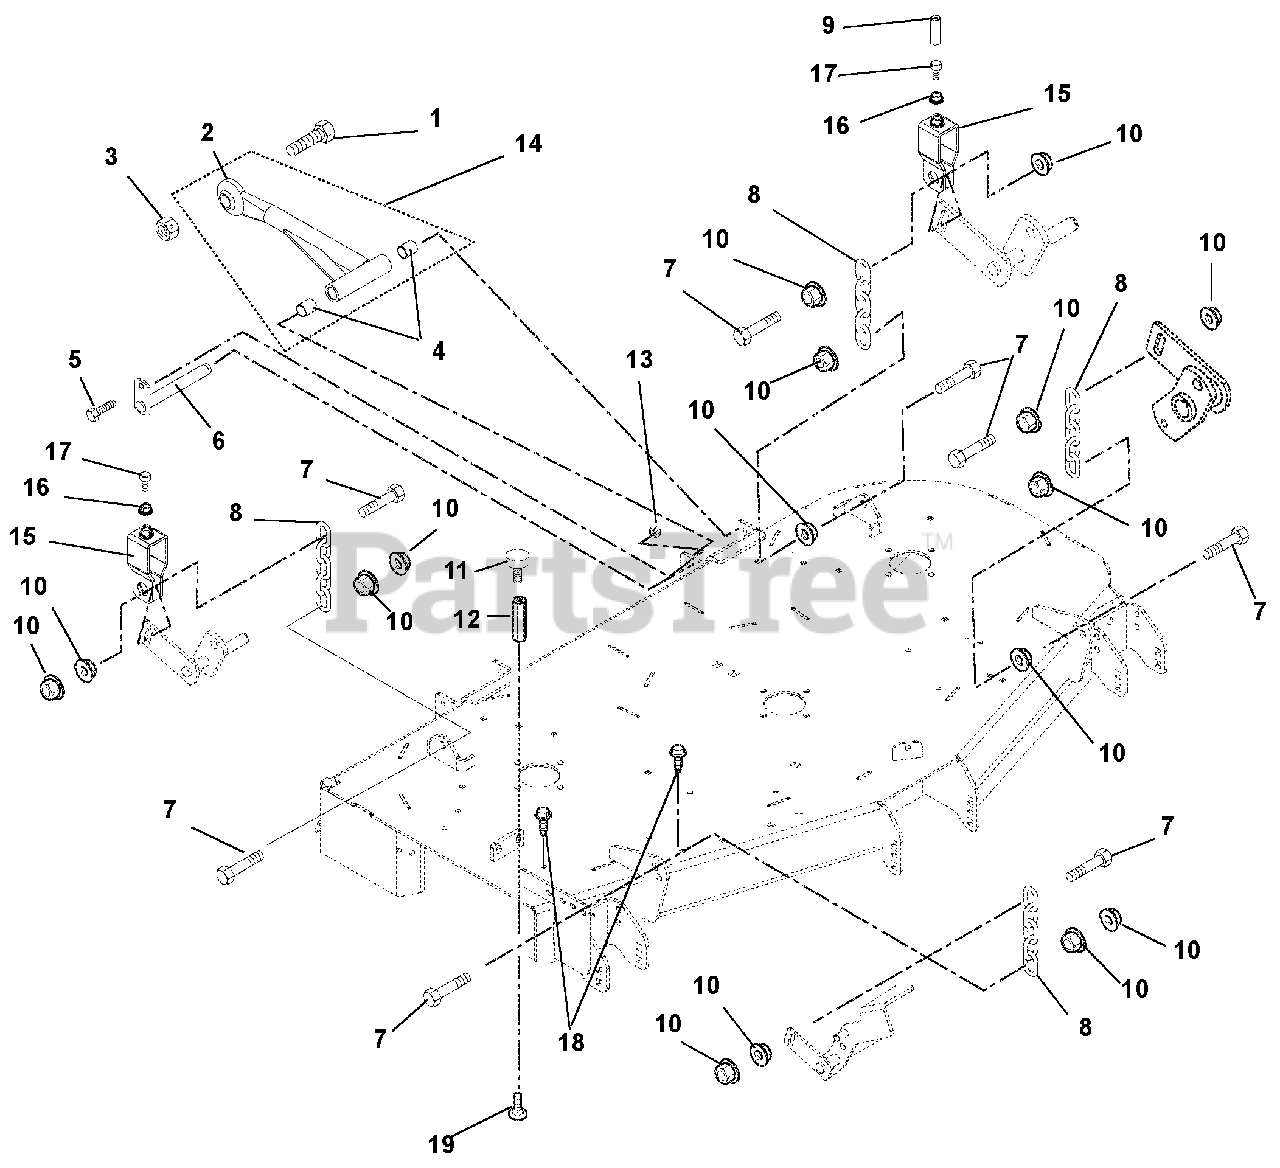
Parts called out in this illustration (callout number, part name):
1	Bolt, Hex .875-9 x 2.75 Grade 5
2	Mower Mounting Arm Weldment
3	Nut, Locking Center .875-9
4	Bearing, .75 x .875 x 1.00
5	Bolt, Hex .38-16 x 1.00 Grade 5
6	Weldment, Mower Mounting Pin
7	Bolt, Hex M12-1.75 x 50 Grade 5
8	Chain, Link
9	Cap, Vinyl .50 ID x 1.50LG x .055
10	Nut, Spin Lock Flange M12-1.75
11	Bumper, Rubber
12	Nut, Coupling .31-18 x 3.00
13	Nut, .38-16 Nyloc Flange
14	Assembly, Mower Mounting Arm (Includes item # 2 and item # 4)
15	Bracket, Deck Leveling
16	Nut, Jam .312-18
17	Bolt, Full Thread Hex .312-18 x 2.00
18	Screw, Tapping Hex Washer Head Thread .38-16 x .50
19	Bolt, Round Head Square Neck .31-18 x .75
